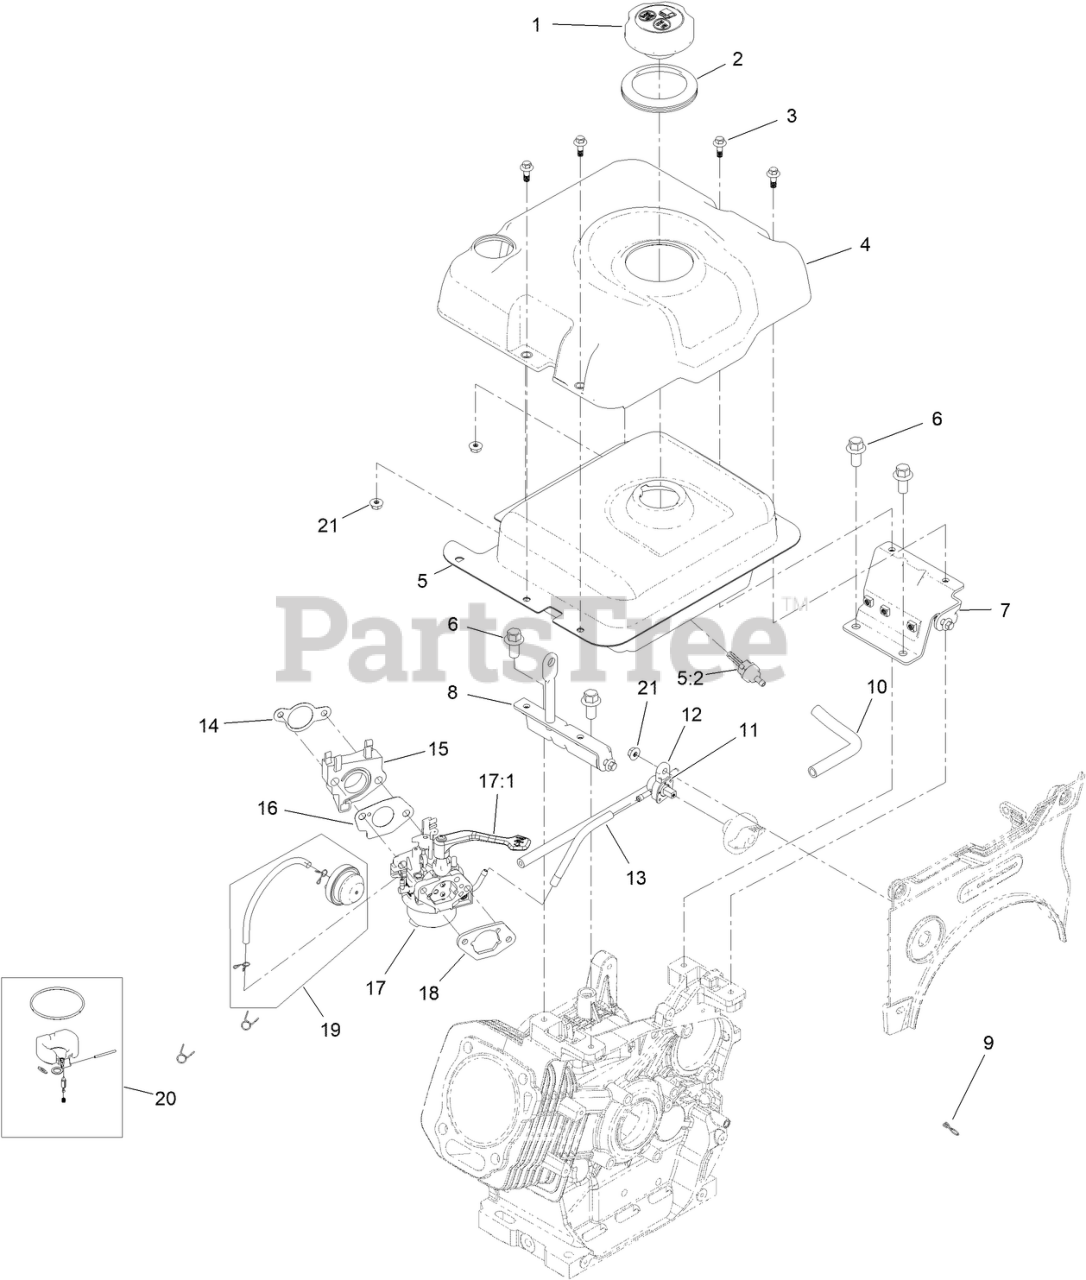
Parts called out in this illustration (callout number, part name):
1	CAP-FUEL
2	INSERT-COVER, TANK
3	SCREW-HHF
4	COVER-TANK, FUEL
5	FUEL TANK AND FILTER ASM
5:2	FILTER-FUEL
6	SCREW-HHF
7	BRACKET-TANK, RIGHT
8	BRACKET-TANK, LEFT
9	CLIP-HOSE
10	SLEEVE-ABRASION
11	HOSE-FUEL
12	VALVE-FUEL
13	HOSE-FUEL
14	GASKET-CARBURETOR
15	INSULATOR-CARBURETOR
16	GASKET-CARBURETOR
17	CARBURETOR ASM
17:1	LEVER-CHOKE
18	GASKET-COATED, RUBBER
19	PRIMER KIT
20	INTERNAL CARB SERVICE KIT
21	NUT-FLANGE
